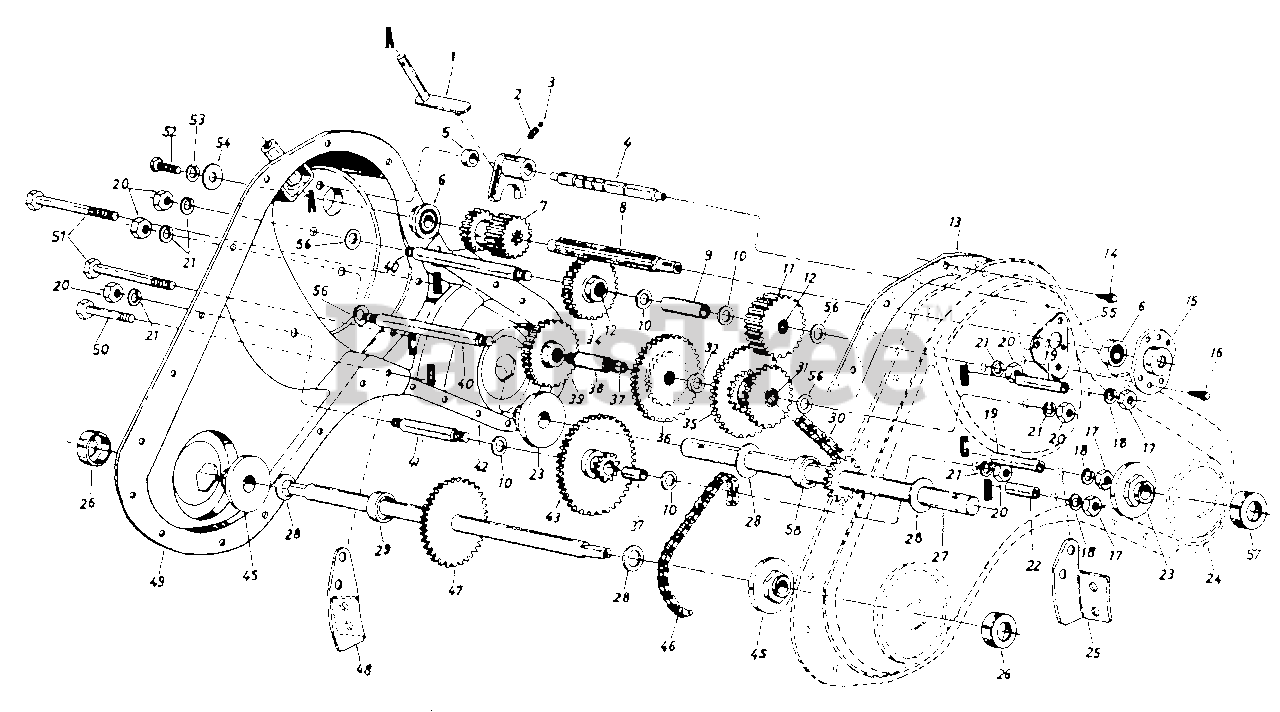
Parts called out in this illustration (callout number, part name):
1	BRACKET ASSY-SHIFT
2	SPRING-COMPRESSION
3	BALL-DETENT
4	SHAFT-DETENT
5	SPACER-.505 1D
6	BEARING-BALL
7	GEAR-SPUR-16T
8	SHAFT-INPUT
10	WASHER-FL-.640ID X 1.24OD X .06HDN
11	GEAR-SPUR-30T
12	BEARING-NEEDLE
14	SCREW-HEX WASH SF TAPP
15	HOUSING-BRG
16	SCREW-HEX HD TAP 1/4-20 X 7.5
17	NUT-HEX 5/16-18
18	WASHER-LOCK-5/16
19	SPACER-1.560 1D
20	NUT-HEX 7/16-20
21	WASHER-FL
22	SPACER-1.015 1D
23	BEARING
24	HOUSING ASSY-LH
27	SHAFT ASSY-TINE
28	WASHER-FL-1.03 ID X 1.62 X .03 HD
29	SPACER
30	#50 CHAIN 5/8 PITCH X 52L E
31	BEARING-NEEDLE
32	WASHER-FL
34	GEAR-SPUR-30T
35	GEAR-30/44T
36	GEAR-SPUR-44T
37	BEARING-SLEEVE .627 X .750 X .936
39	GEAR-SPUR-30T
40	JACKSHAFT
41	JACKSHAFT
46	#420 CHAIN-1/2 PITCH
47	SHAFT ASSY-WHEEL
51	SCREW-HEX
52	BOLT - 1/4-28 X 5/8 61.5
53	WASHER-LOCK-3/8
54	WASHER-FL
55	BRACKET-GEAR POS
56	WASHER-FL
57	COVER-DUST
58	SPACER
